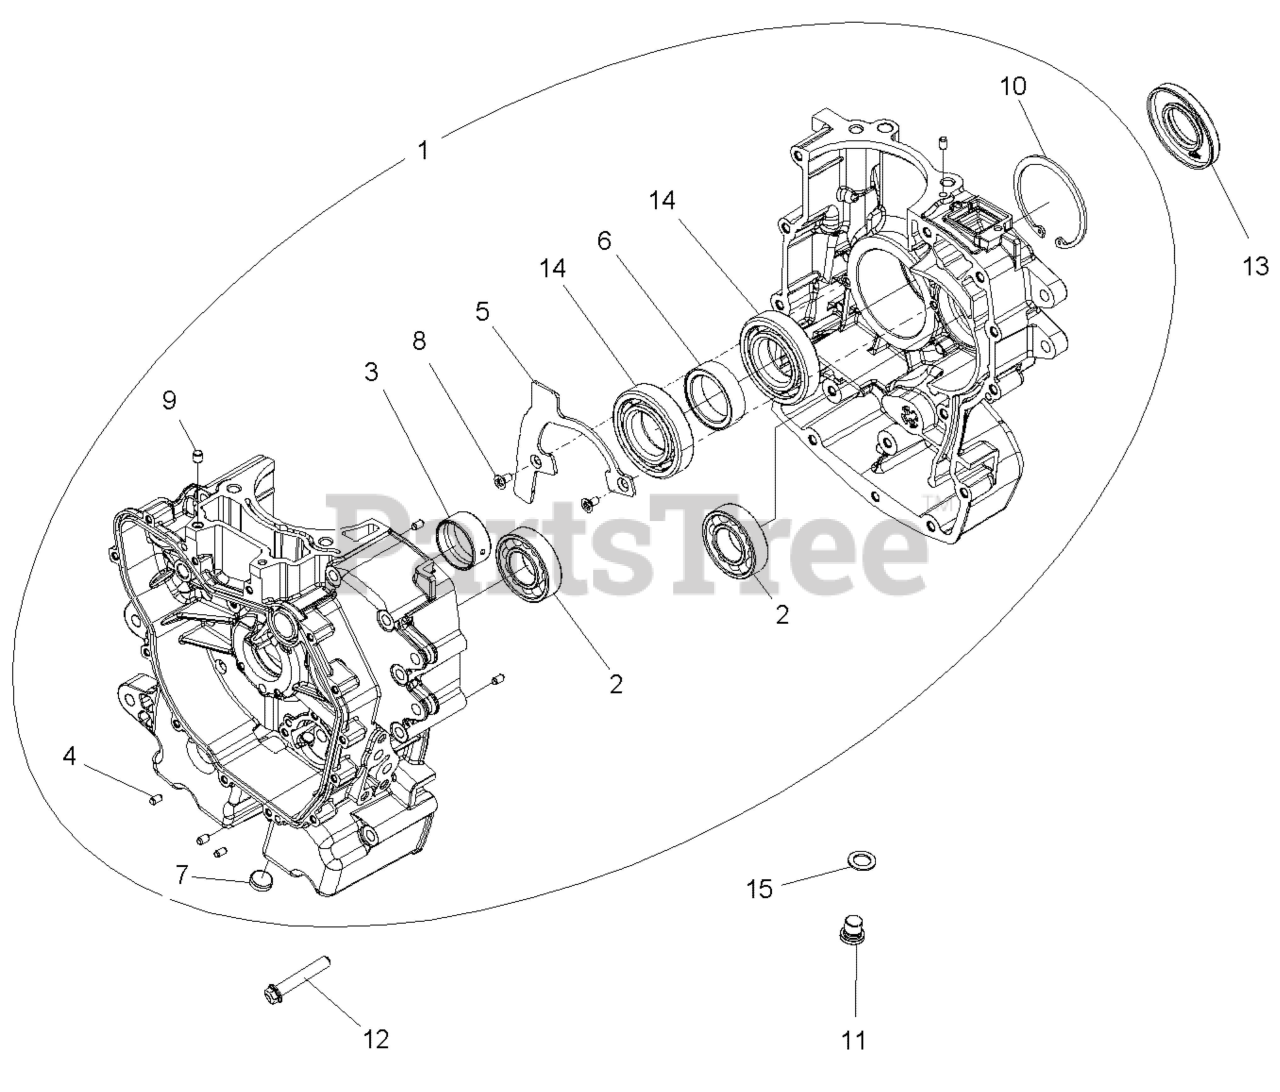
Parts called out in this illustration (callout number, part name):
1	KIT, CRANKCASE
2	BEARING-BALL,30X62X16
3	BEARING, MAIN
4	PIN-DOWEL,M6X10
5	PLATE-BEARING RETAINER
6	SPACER, BEARING
7	PLUG,EXPANSION,19MM
9	DWL-HOL,M8X10
10	RING-SNAP,80X2.5
11	PLUG-SOCKET,M12X1.5 DIN 908A
12	SCR-M8X1.25X90
13	SEAL-CRANKSHAFT
14	BEARING-BALL 40X80X18 DG NCAGE
15	WASHER-19X12X1.3-COPPER (10)
